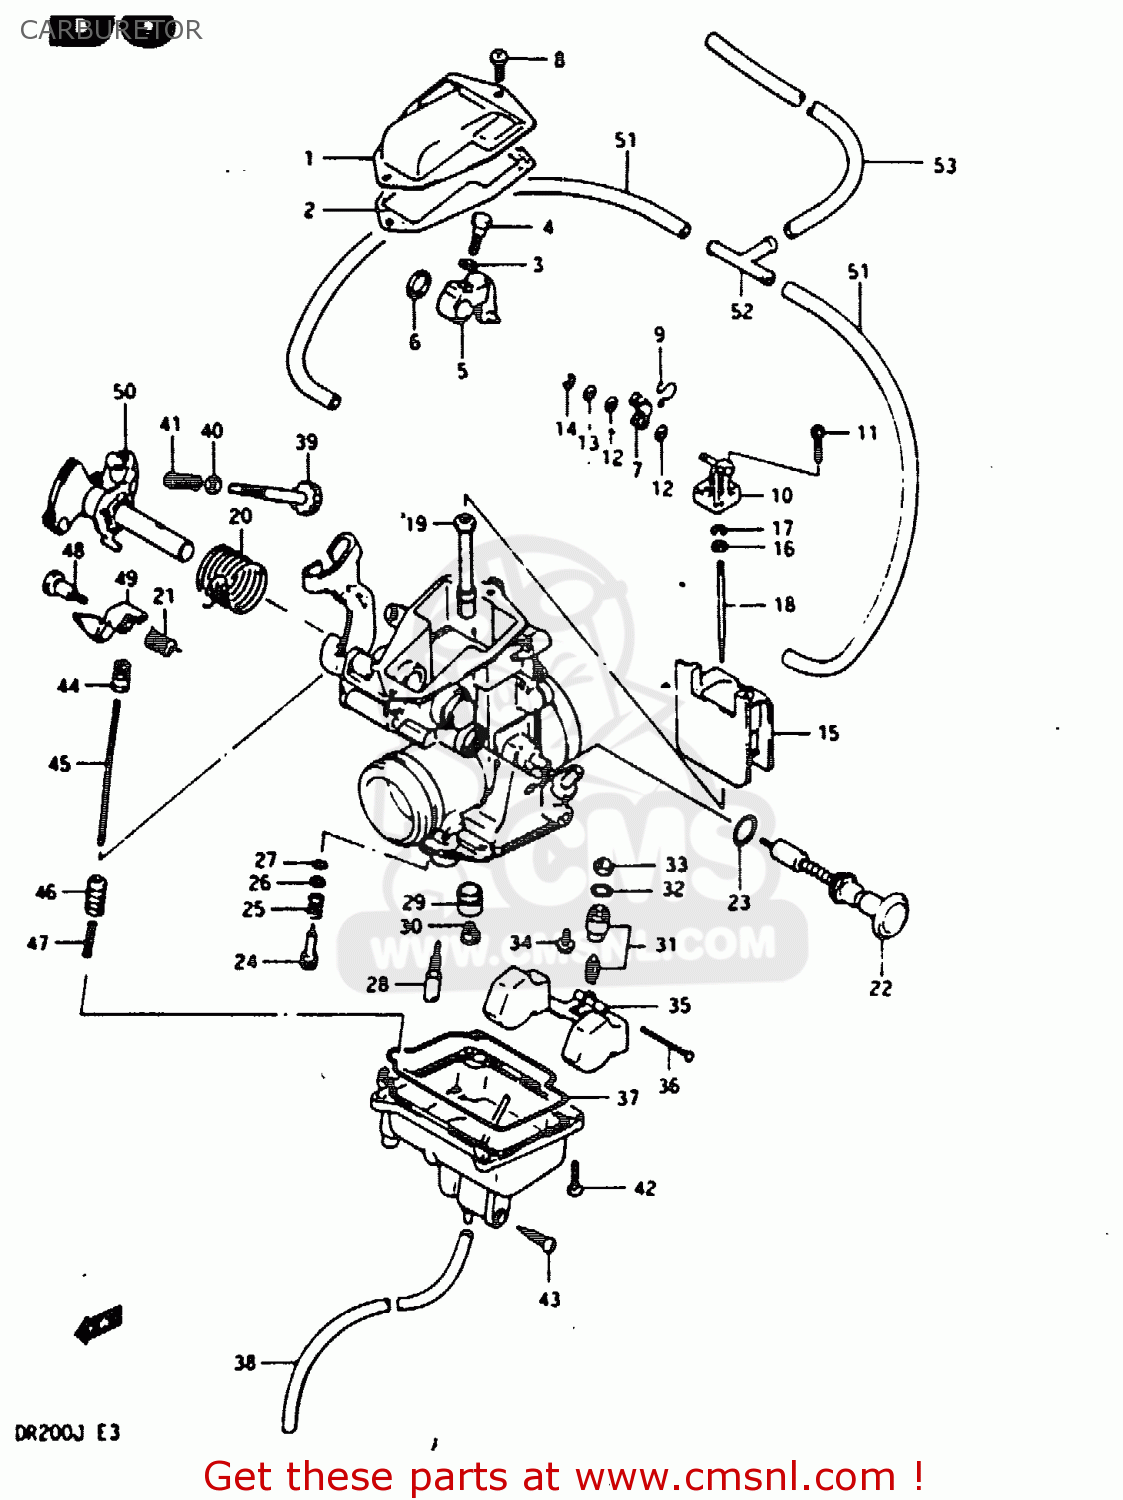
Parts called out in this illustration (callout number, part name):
1	COVER,CARBURETOR,TOP
2	GASKET,CARBURETOR TOP (NAS)
3	WASHER
4	BOLT
5	ARM,THROTTLE
6	RING,THROTTLE SHAFT
7	PLATE
8	SCREW
9	SPRING
10	CONNECTOR
11	SCREW
12	GASKET (NAS)
13	WASHER
14	E-RING
15	VALVE,THROTTLE
16	WASHER,JET NEEDLE
17	CLIP
18	NEEDLE,JET
19	JET,NEEDLE (P-6)
20	SPRING
21	SPRING,PLUNGER
22	PLUNGER ASSY
23	O RING
24	SCREW,PILOT
25	SPRING
26	GASKET
27	O-RING
28	JET
29	RING,MAIN JET FIXING
30	JET,MAIN(115)
31	VALVE ASSEMBLY,NEEDLE
32	O RING
33	FILTER
34	SCREW
35	FLOAT
36	PIN,FLOAT
37	O RING,FLOAT CHAMBER
38	HOSE
39	SCREW,THROTTLE STOP
40	WASHER
41	SPRING
42	SCREW
43	SCREW,DRAIN
44	BOOT, ACCELE PUMP ROD
45	ROD,PLUNGER
46	PLUNGER
47	SPRING
48	BOLT
49	LEVER
50	SHAFT ASSEMBLY
51	HOSE
52	JOINT,3 WAY
53	HOSE
